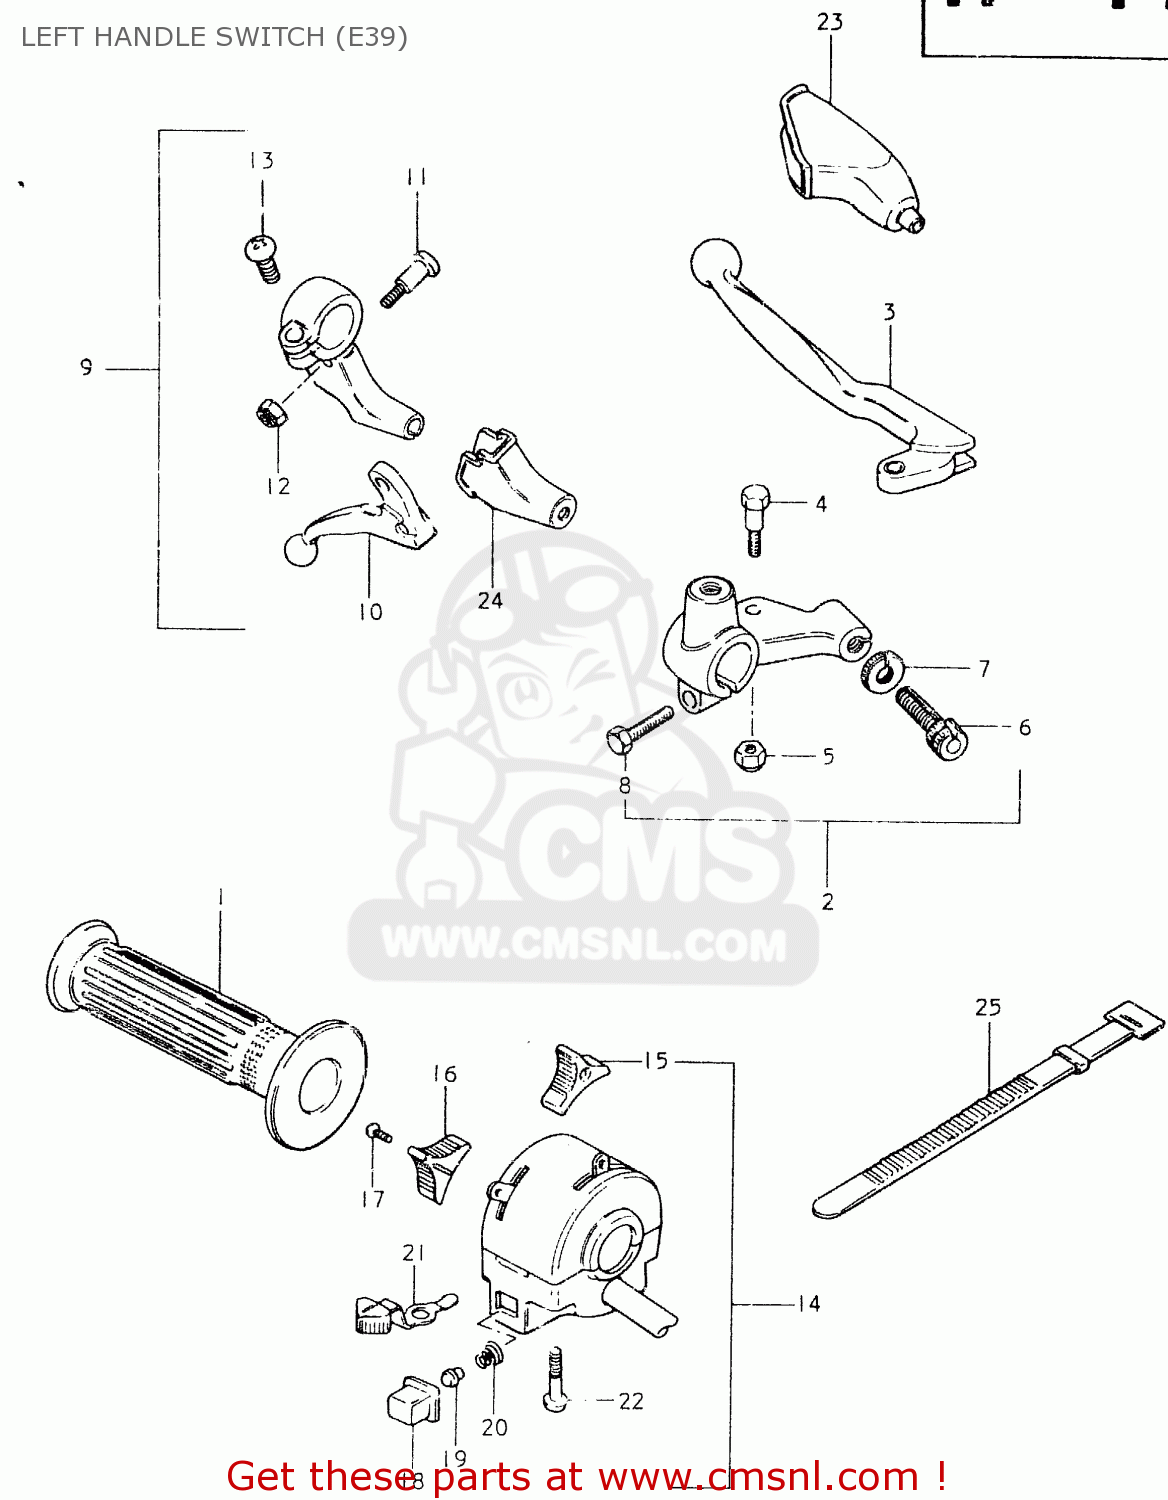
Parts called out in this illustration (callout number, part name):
1	GRIP,L
2	LEVER ASSY,CLUTCH
3	LEVER,CLUTCH
4	BOLT,LEVER
5	NUT 6MM
6	ADJUSTER,CABLE
7	NUT,CABLE ADJUSTER
8	BOLT
9	LEVER ASSEMBLY,DECOMPRESSION
10	LEVER,DECOMPRESSION
11	BOLT,LEVER
12	NUT,LEVER BOLT
13	SCREW
14	SWITCH ASSY, HANDLE LH
15	KNOB,LIGHTING SWITCH
16	KNOB, DIMMER
17	SCREW
18	BUTTON,HORN
19	CONTACT
20	SPRING
21	KNOB,TURNSIGNAL
22	SCREW
23	COVER,CLUTCH LEVER
24	DUST COVER,DECOMPRESSION LEVER
25	CLAMP(L:120)
